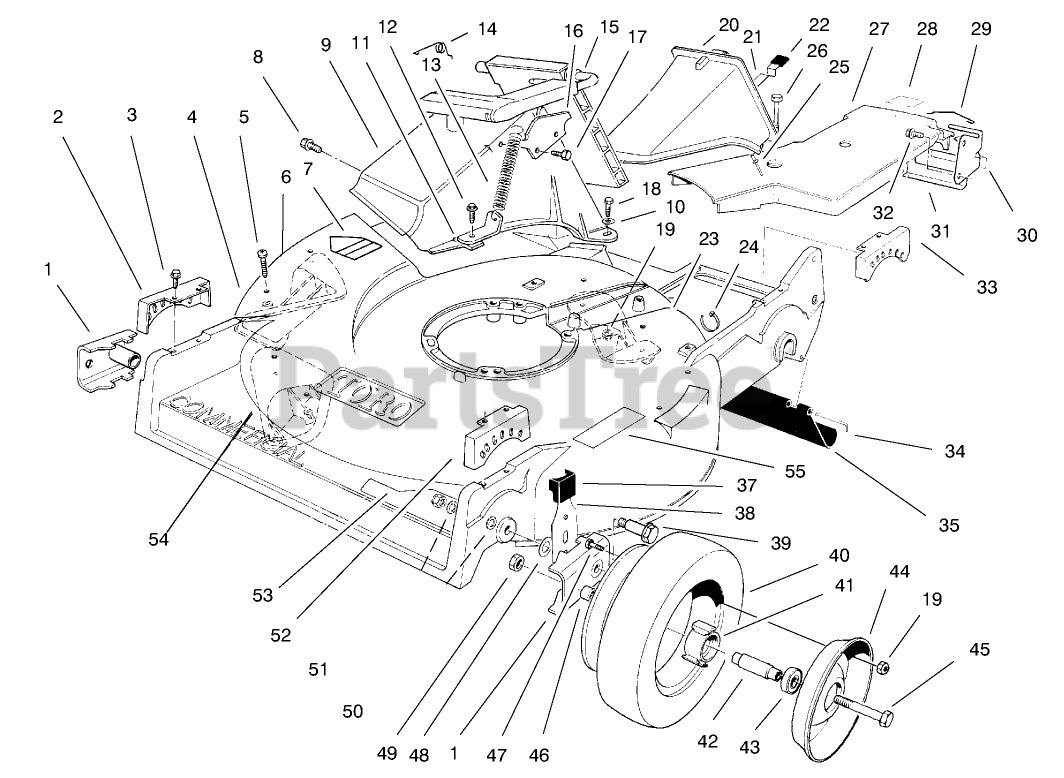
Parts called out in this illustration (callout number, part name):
1	ARM-PIVOT, FRONT
2	QUADRANT-FRONT, RH
3	SCREW-HWHTF
4	HOUSING W/DECALS
5	SCREW-PPH
6	KICKER-RH
7	DECAL-DANGER
8	SCREW AND WASHER ASM
9	DISCHARGE TUNNEL
10	WASHER-FLAT
11	BRACKET-SPRING
12	SCREW-HWH
13	SPRING-DOOR
14	RETAINER-DOOR
16	DOOR LATCH PLATE
17	SCREW-PLASTITE
18	SCREW-HH
19	NUT-LOCK, NI
20	DISCHARGE PLUG ASM
21	LATCH-PLUG, DISCHARGE
22	GRIP-LATCH
23	KICKER-REAR
24	TIE-CABLE
25	RIVET-HEAD, FLAT
26	SCREW-HWH
27	COVER-BELT
29	RETAINER-CABLE
30	DECAL-POSITION, GEAR
31	BRACKET-ADJUSTMENT, TRACTION
32	SCREW-HWHTF
33	QUADRANT-REAR, LH
34	ROD-SHIELD
37	KNOB-ARM
38	FRONT SPRING ARM ASM
41	HUB-BEARING
42	SPACER-BEARING
43	BEARING-WHEEL
45	SCREW-HH
46	SPACER-WHEEL
47	SCREW-HH
48	WASHER-THRUST
49	NUT-LOCK, CONE
50	WASHER
51	NUT-LOCK
52	QUADRANT-FRONT, LH
53	DECAL - RECYCLER
54	KICKER-FRONT
55	DECAL-INSTRUCTION, SAFETY
